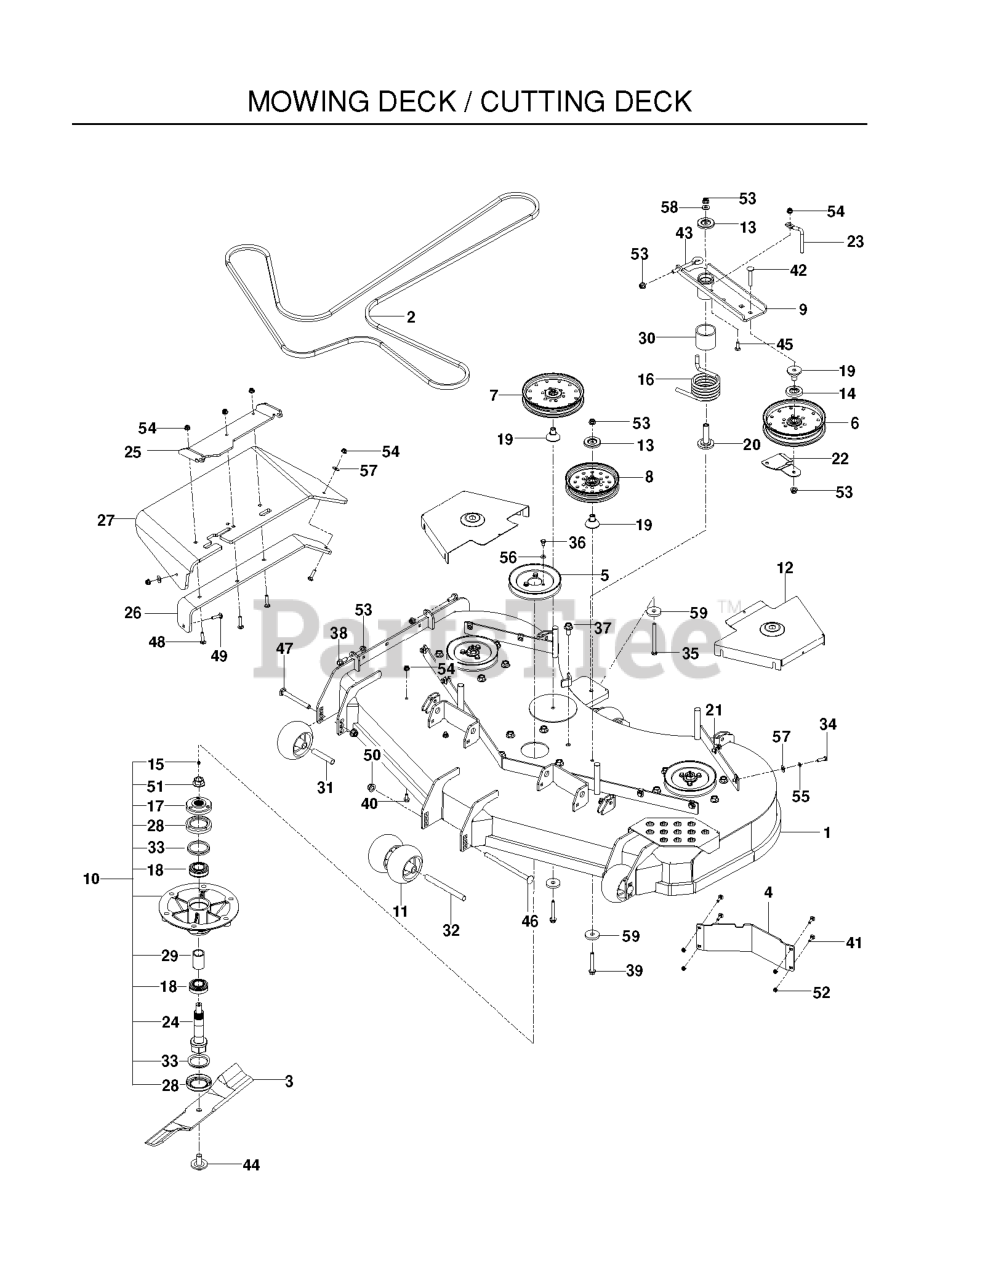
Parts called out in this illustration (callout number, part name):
1	DECK.SVC W/DECALS.60.ORANGE
2	RP.BELT, "5V", 176"
3	BLADE - HEAVY DUTY 21"
4	BAFFLE, DIVERTER 54"/60" LH
5	PULLEY - 6.57
6	PULLEY - IDLER 7"
7	PULLEY - 7" NARROW
8	PULLEY IDLER, 6" NARROW
9	ASSY, IDLER ARM, PZ
10	SPINDLE ASM. 10"
11	ROLLER, GAUGE .635 BORN
12	SHIELD,BELT, 60" ORANGE
13	DUST SHIELD
14	SHIELD, DUST
15	ZERK
16	SPRING, TORSION, IDLER
17	HUB - PULLEY
18	BEARING - 206KRR8
19	BEARING, IDLER ARM
20	BEARING, IDLER PIVOT
21	U-CLIP 5/16-18 NUT RETAINER
22	BELT.GUIDE.BLACK
23	BELT KEEPER
24	SHAFT - SPINDLE
25	BRKT - CHUTE MTG BLACK
26	BRKT, CHUTE SUPPORT BLACK
27	CHUTE, DISCHARGE 48-52
28	CUP - DEBRIS
29	SPACER - BEARING
30	SPACER, IDLER PIVOT
31	TUBE, ROLLER AXLE
32	TUBE, ROLLER AXLE LONG
33	V-RING, 55MM
34	HCS 5/16C X 1
35	HCS 3/8-16 X 4-1/2 GR 8 ZD
36	HCS 5/16-18 X 1/2 GR 5 ZD
37	HHFS 1/2-13 X 1 GR5 ZD
38	HHFS 3/8-16 X 1 GRD 5 ZD
39	HHFS 3/8-16 X 2 3/4
40	HHFS 5/16-18 X 3/4
41	1/4-20X3/4 CARR BLT
42	CARRIAGE BOLT 3/8-16 X
43	EYE BOLT, 3/8 X 4"
44	BLADE BOLT/WASHER
45	RHSSNB 5/16C X 1.0
46	RHSNB 1/2-13 X 8 GR5 ZD
47	RHSNB 1/2-13 X 4.75 GR5 ZD
48	RHSNB 5/16-18 X 1-1/2 GR 5 ZD
49	BOLT, CARRIAGE 5/16X1-1/4
50	NUT, 1/2-13 HEX FLG NYLOC ZD
51	NUT FLANGE 3/4-16
52	NUT.1/4-20.HEX.NYLOC.ZD
53	NUT 3/8-16 HEX FLG NYLOC ZD
54	5/16-18 NYLOC FLANGE NUT
55	WASHER.LOCK.HVY.HLCL.SPR.5/16
56	WASH 5/16 DISC SPRING ZD
57	WASHER 5/16 FLAT
58	WASHER, 3/8 THICK
59	SPINDLE WASHER
